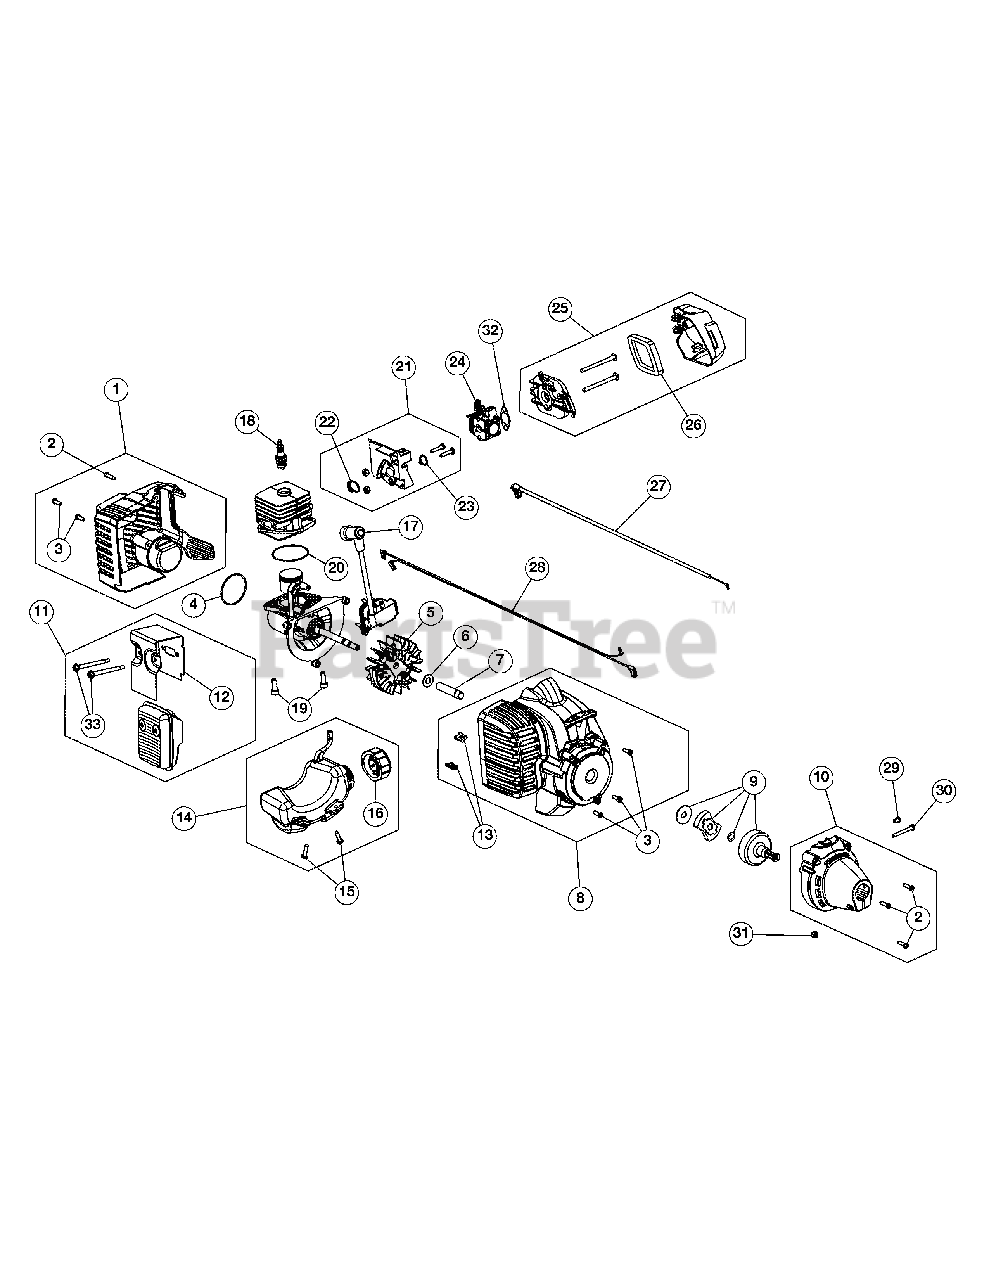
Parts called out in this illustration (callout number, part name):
1	Rear Cover Assembly (Incl. 2 & 3)
2	Cover Screw
3	Housing Screw
4	O-Ring
5	Flywheel Assembly
6	Washer
7	Spacer
8	Starter Housing (Incl. 3 & 13)
9	Starter Clutch Assembly
10	Clutch Cover (Incl. 2)
11	Muffler Assembly (Incl. 12 & 33)
12	Muffler Gasket
13	U-shaped Nut
14	Fuel Tank Assembly (Incl. 15 & 16)
15	Tank Screw
16	Fuel Cap
17	Module Assembly
18	Spark Plug
19	Crankcase Bolt
20	Crankcase O-Ring
21	Insulator Assembly (Incl. 22 & 23)
22	Insulator O-Ring
23	Carburetor O-Ring
24	Carburetor
25	Aircleaner Cover Assembly (Incl. 26)
26	Aircleaner Filter
27	Throttle Cable
28	Lead Wires
29	Anti-rotation Screw
30	Clamp Screw
31	Clamp Nut
32	Air Cleaner Gasket
33	Muffle Screws
